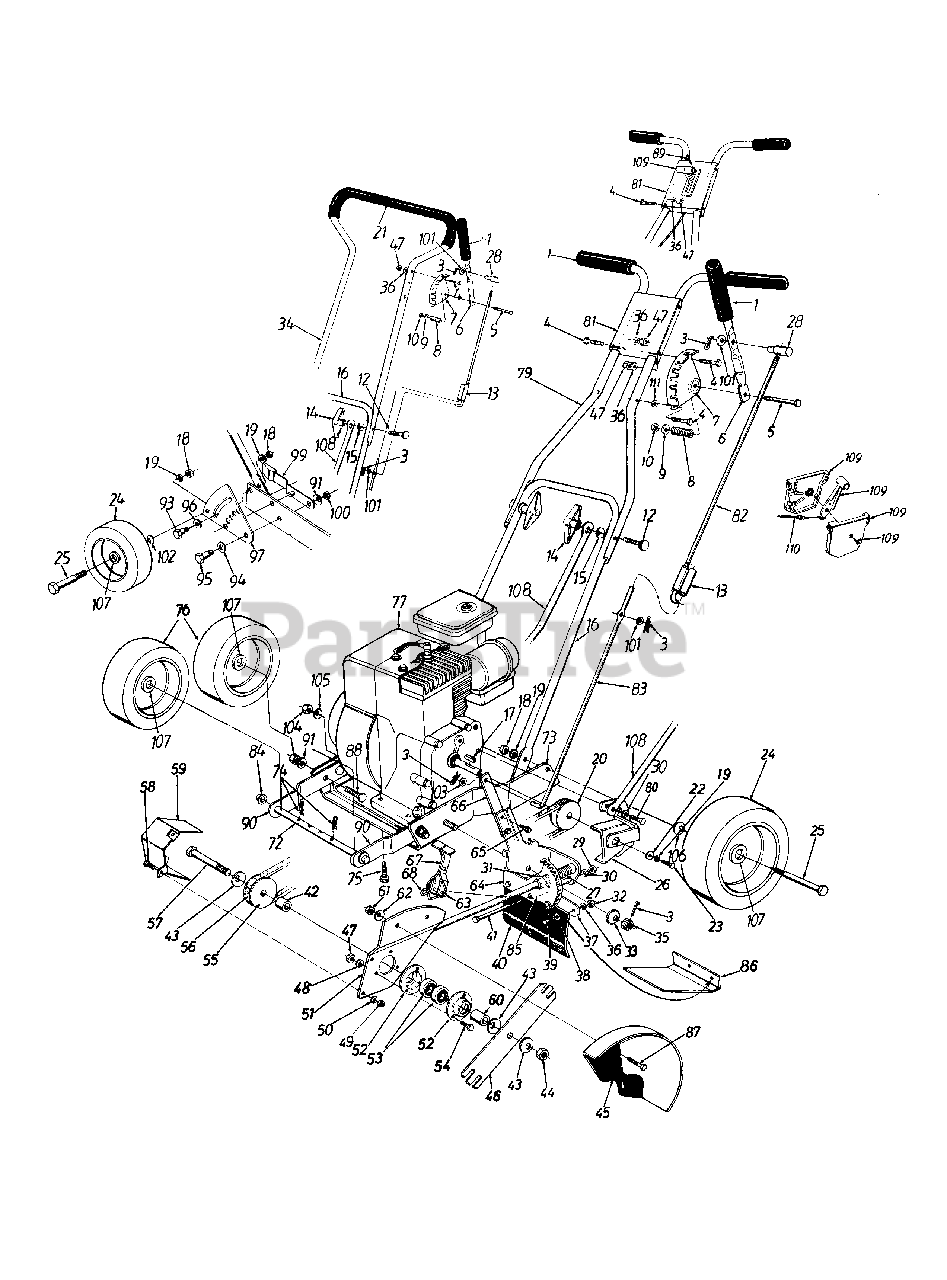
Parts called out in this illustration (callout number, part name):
1	Foam Grip
2	Hex L-Nut 1/4-20 Thd.
3	Cotter Pin 5/16" Dia.
4	Hex Bolt 1/4-20 x 1.25" Lg.
5	Hex Bolt 5/16-18 x 2" Lg.
8	Compression Spring 1.38" Lg.
9	Fl-Wash. .344" I.D.
10	Hex L-Nut 5/16-18 Thd.
12	Curv. Hd. Bolt 5/16-81 x 2" Lg.
13	Clutch Rod Lock
14	Wing Nut Ass'y.
15	Saddle Wash. .32" I.D. x .937"
18	Hex Nut 3/8-16 Thd.
19	L-Wash. 3/8" I.D.
20	Engine Pulley
21	Foam Grip
22	Fl-Wash. .385" I.D.
23	Hex Bolt 3/8-24 x 1" Lg.
24	Rear Wheel Ass'y. - Bar Tread
25	Shoulder Bolt .498" Dia.
28	Ferrule
29	Hex Nut 5/16-18 Thd.
30	L-Wash. 5/16" I.D.
31	Spring Pin Spir. 1/4" Dia.
32	Hex Nut 1/4-20 Thd.
33	Bell-Wash. .535" I.D.
34	Upper Loop Handle
35	Hex Slotted Nut 1/2-20 Thd.
36	L-Wash. 1/4" I.D.
39	Hex Bolt 1/4-20 x .62" Lg.
41	Hex Bolt 5/16-18 x 4.5" Lg.
42	Spacer 1.030" Lg.
43	Bell-Washer. .63" I.D.
44	Hex Jam L-Nut 5/8-18 Thd.
47	Hex Nut 1/4-20 Thd.
48	L-Wash. 1/4" I.D.
49	Hex Nut 1/4-20 Thd.
50	L-Wash. 1/4" I.D.
53	Ball Bearing .62" I.D.
54	Hex Bolt 1/4-20 x .62" Lg.
55	3/8" "V"-Pulley
56	"V"-Belt
57	Hex Bolt 5/8-18 x 4.5" Lg.
58	Hex Bolt 1/4-20 x . 625" Lg.
60	Sleeve .90" Lg.
61	Hex Nut 5/16-18 Thd.
62	Bell-Wash. .345" I.D.
63	Spring Pin Spir. 1/4" Dia.
68	Torsion Spring
69	Hex Nut 5/16-18 Thd.
70	L-Wash. 5/16" I.D.
72	Axle 8.20" Lg. (Front)
75	Hex TT-Tap Scr. 3/8-16 x 1" Lg.
76	Front Wheel Ass'y. - Bar Tread
77	Engine
83	Lower Clutch Rod
84	Push Cap 1/2" Dia.
85	Spacer 3.765" Lg.
88	Ribbed Neck Bolt 3/8-24 x .8: Lg.
89	Self-Tap Scr. #10 x .5" Lg.
92	Fl-Wash. .39" I.D.
93	Shld. Bolt .5" Dia.
94	Bell-Wash. .515" I.d.
95	Shld. Bolt .50" Dia.
96	Fl-Wash. .51" I.d. x .94"
100	Hex Jam Nut 3/8-16 Thd.
101	Fl-Wash. .344" I.D. x .62" O.D.
102	Wave Wash. .51" I.D.
103	Fl-Wash. .406" I.D. x .81" O.D.
104	Hex Nut 3/8-24 Thd.
105	Bell-Wash. .396" I.D. x 1.14" O.D.
106	Bell-Wash. .38" I.D. x .88" O.D.
107	Plastic Bearing
110	Throttle Wire 39" Lg.
111	Fl-Wash. .25" I.D. x .62" O.D.
